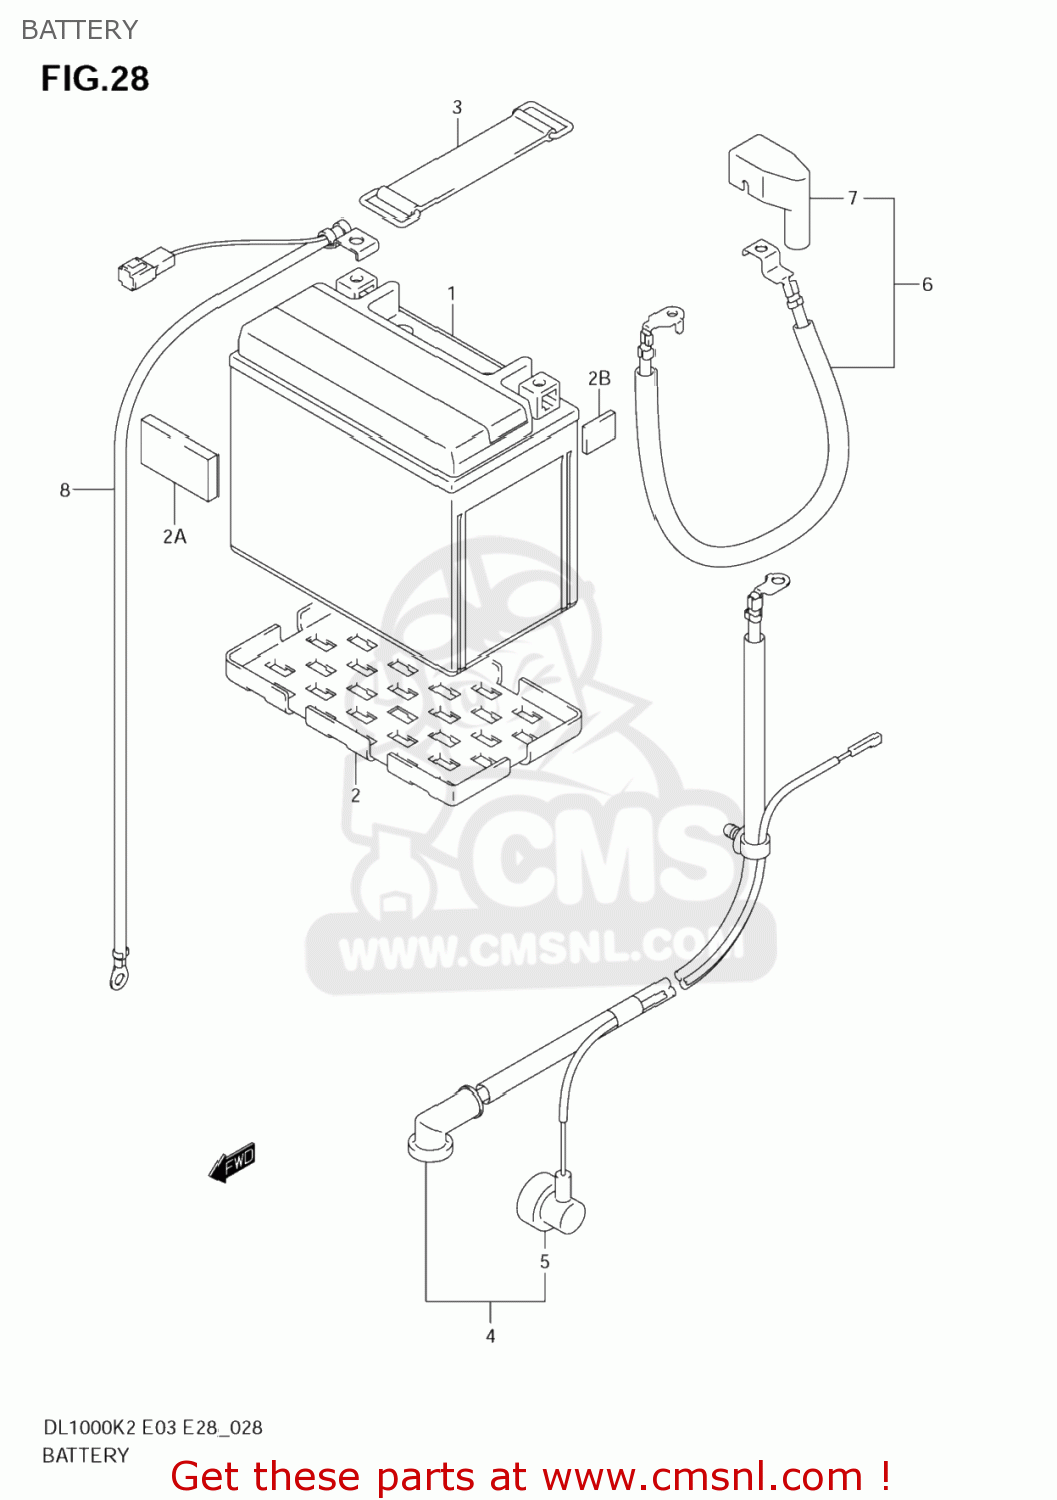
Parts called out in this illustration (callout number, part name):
1	BATTERY ASSY (12V) YTX14-BS
2	PROTECTOR,BATT
2A	PROTECTOR,BATTERY(70X100X6)
2B	PROTECTOR(170X95X3.0)
3	BAND
4	WIRE,STARTER MOTOR LEAD
5	CAP,OIL PRESSURE SWITCH
6	WIRE,BATTERY PLUS LEAD
7	CAP,BATTERY PLUS LEAD
8	WIRE,BATTERY MINUS LEAD
